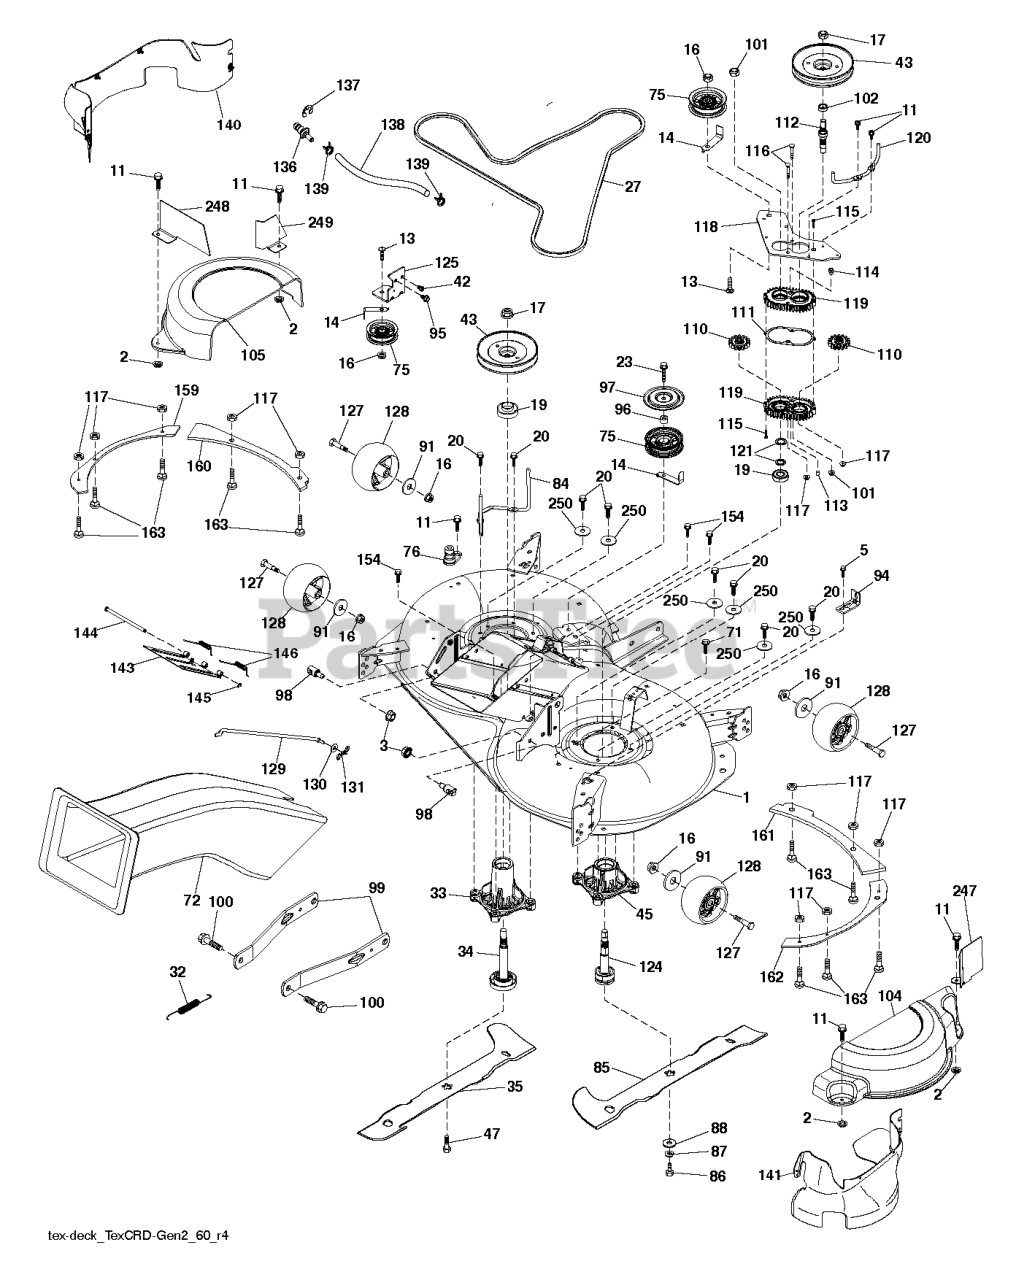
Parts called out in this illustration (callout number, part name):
1	DECK SVC 107HP.EZMUL.498
2	PALNUT 1/4
3	NUT LOCK HEX FLANGE 5/16-18
5	BOLT.5/16HEX.WHS.HD
11	SCREW.1/4-20X5/8
13	BOLT.3/8-16X1.50
14	KEEPER, BELT IDLER
16	NUT LOCK FLG 3/8-16 UNC
17	NUT.FLANGE.LOCK.TOP
18	WASHER.SPACER.MANDREL
20	SCREW, WASHER HEAD
23	SCREW LT
27	BELT BELT. ELECTRIC MOWER DRIV
32	SPRING 107CM & 97CM ELECTRIC D
33	RP.HOUSG.MAND.REV.TALL.N/GRS
34	RP.SAFT ASM.REV.TALL.N/GREASE
35	BLADE.107.LH.SINGLE.NON.QD
36	BOLT.WASHER.ASM.7/16-2
42	SCREW
43	PULLEY PULLEY MANDREL 5.438 PD
45	RP HOUSING.MANDREL.REV.REVS.
71	SCREW 3/8-16X1/2
72	RP.CHUTE 107/97 TEX GENII
75	FLAT IDLER PULLEY
76	1/2" BARB.DECK.WASHOUT.PORT
84	KEEPER KEEPER. LH MANDREL BELT
85	BLADE.107.RH.SINGLE.NON.QD
86	BOLT.3/8-24X1.25GR8. LHTHRD
87	LOCKWASHER
88	WASHER.BLADE
91	WASHER
94	BRKT.CLUTCH.CABLE
95	SCREW, 3/8-16X3/4
96	SPACER
97	PROTECTOR
98	STUD.FASTNER.W/ANTI-ROTATE
99	ARM.SUSPENSION.MOWER.R
100	BOLT.SHOULDER
101	NUT.CROWNLOCK.9/16 -18.UNC
102	SPACER BEARING
104	COVER.MANDREL.107.RH.GEN.2
105	COVER.MANDREL.107.LH.GEN.2
110	CRD.SPUR.GEAR
111	GASKET GASKET GEARCASE
112	SHAFT SHAFT. CRD GEARCASE ADAP
113	PLUG PLUG OIL
114	VALVE VALVE RELIEF
115	SCREW
116	BOLT.CARIGE.SS.1/4-20X1.75GR5
117	NUT T
118	ARM ARM. CLUTCHING 107 TEX CRD
119	GEARCASE GEARCASE SUBASM
120	KEEPER KEEPER. RH MANDREL BELT
121	WASHER WASHER
124	SUB.ASM.REVERSE.THREAD.REV
125	BRACKET
127	BOLT.SHOULDER.3/8-16X3-5/8.
128	RP WHEEL. GUAGE RALLY
129	ROD ROD. SWAY CRD GEN II
130	WASHER
131	PIN.COTTER.5/16.BOW TI
136	PLUG WASHOUT PORT HOOKUP
138	107.WASHOUT.PORT.HOSE (2 2)
139	HOSE.3/8.CLAMP (2 2)
140	GUARD FRENCH 107 TEX ASSEMBLY
141	GUARD SUBASM. 107 TEX GEN 2 RH
143	COVER DOOR.107 CM CRD EZ MULCH
144	PIN PIN.HINGE
145	E-RING.5/16"
146	SPRING SPRING: EZ MULCH DOOR
154	SCREW T-30 1/4-20 X
159	REINFORCE.PLATE.LHS.BOLT.431
160	REINFORCE.PLATE.LH.FT.X431
161	REINFORCE.PLATE.RH.FRT.X431
162	REINFORCE.PLAT.RH.SD.BLT.X431
163	BOLT
247	GUARD.STEEL.CRD.MANDREL.COV.FR
248	GUARD.STEEL.CRD.MANDREL.COV.FR
249	GUARD.STEEL.CRD.MANDREL.COV.FR
